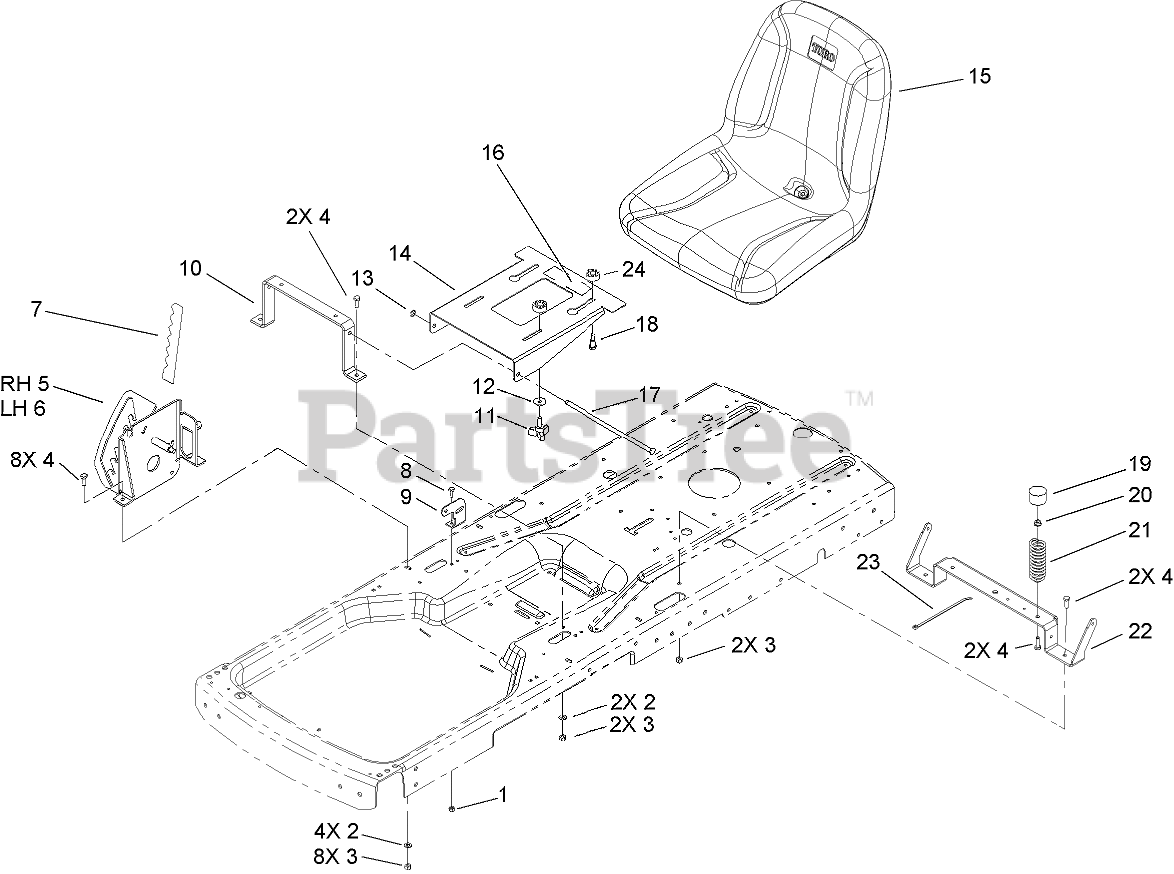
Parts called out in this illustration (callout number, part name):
1	NUT-LOCK, NI
2	WASHER-PLAIN
3	NUT-LOCK, NI
4	SCREW-HH
5	RH PLATE ASM
6	LH PLATE ASM
7	DECAL-HOC
8	SCREW-HH
9	BRACKET-BELLCRANK
10	BRACE-SEAT, FRONT
12	WASHER-PIVOT
13	E-RING
14	BRACKET-SEAT
15	SEAT-18 INCH
16	DECAL-SERVICE, CE
17	PIN-PIVOT
18	SCREW-SHOULDER
19	CAP-PROTECTOR
20	NUT-HF
21	SPRING-COMPRESSION
22	BRACE-SEAT, REAR
23	TIE-CABLE
24	SPACER-NYLON
